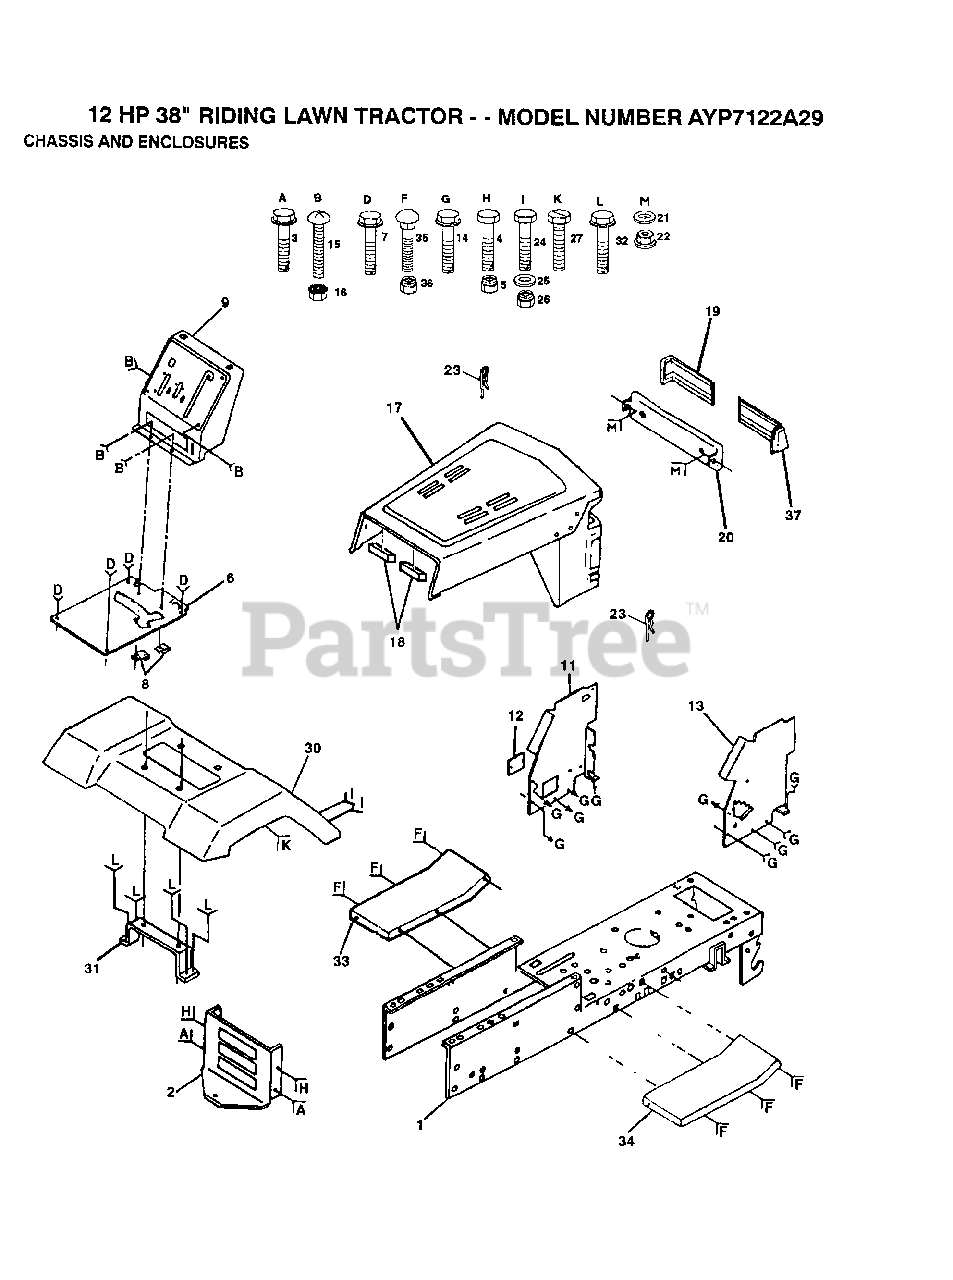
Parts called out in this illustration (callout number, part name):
1	CHASSIS WELDMENT
2	DRAWBAR LT/YT
3	SCREW
7	SCREW LT
8	CLIP T
11	PANEL DASH LH
12	COVER ACCESS
14	SCREW LT
15	SCREW
17	HOOD/GRILL ASM
21	WASHER PM
22	PAL NUT LT
23	SPRING.RETAINER
25	WASHER
27	SCREW LT
30	FENDER
32	SCREW
33	FOOTREST LH
34	FOOTREST RH
35	BOLT
